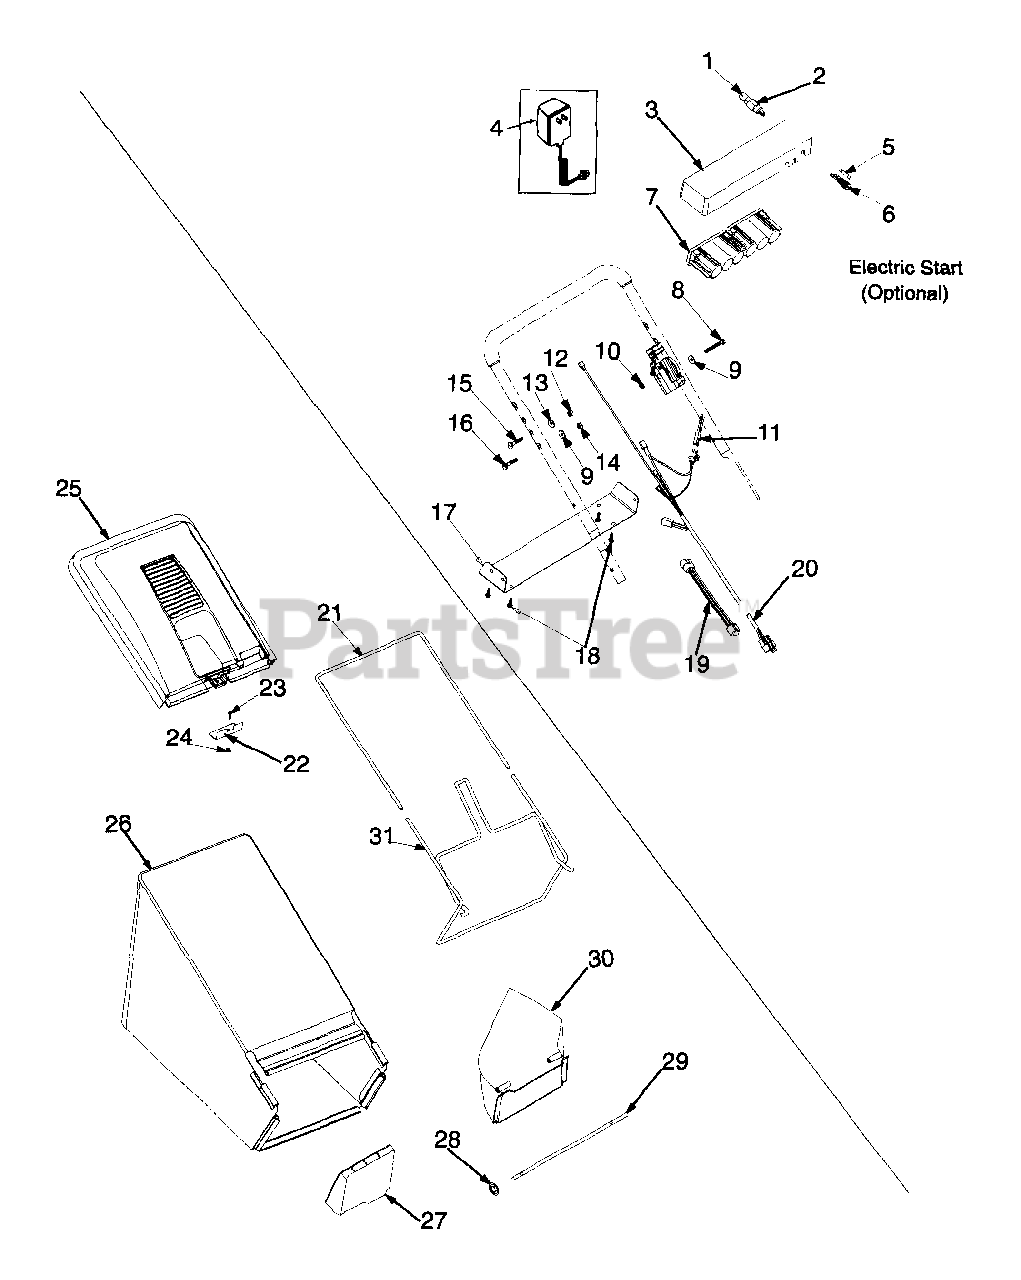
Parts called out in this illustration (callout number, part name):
1	Ignition Key
2	Key Switch
3	Battery Tray
4	Battery Charger
5	Fuse 7.5 Amp
6	Fuse Holder
7	Battery 12V
8	Hex Screw:1/4-20:2.0
9	Bell Washer .265 x .75 x .062
10	Special Hex Nut 5/16-18
11	Plug
12	Nut 5/16-18
13	Bell Wash .340 ID x .872 OD
14	Hex Nut 1/4-20
15	Carriage Bolt 5/16-18 x 1
16	Carriage Screw
19	Harness Extension
20	Harness
23	Hex Screw 1/4 -20 x .5
24	Hex Nylon L-Nut 1/4-20
25	Hardtop Cover w/o Logo: Econo: Blk.
26	Grass Bag: Soft Top w/Logo
27	Mulcher Plug
28	Nut: Spd. .3125 ID
30	Side Discharge Adapter
